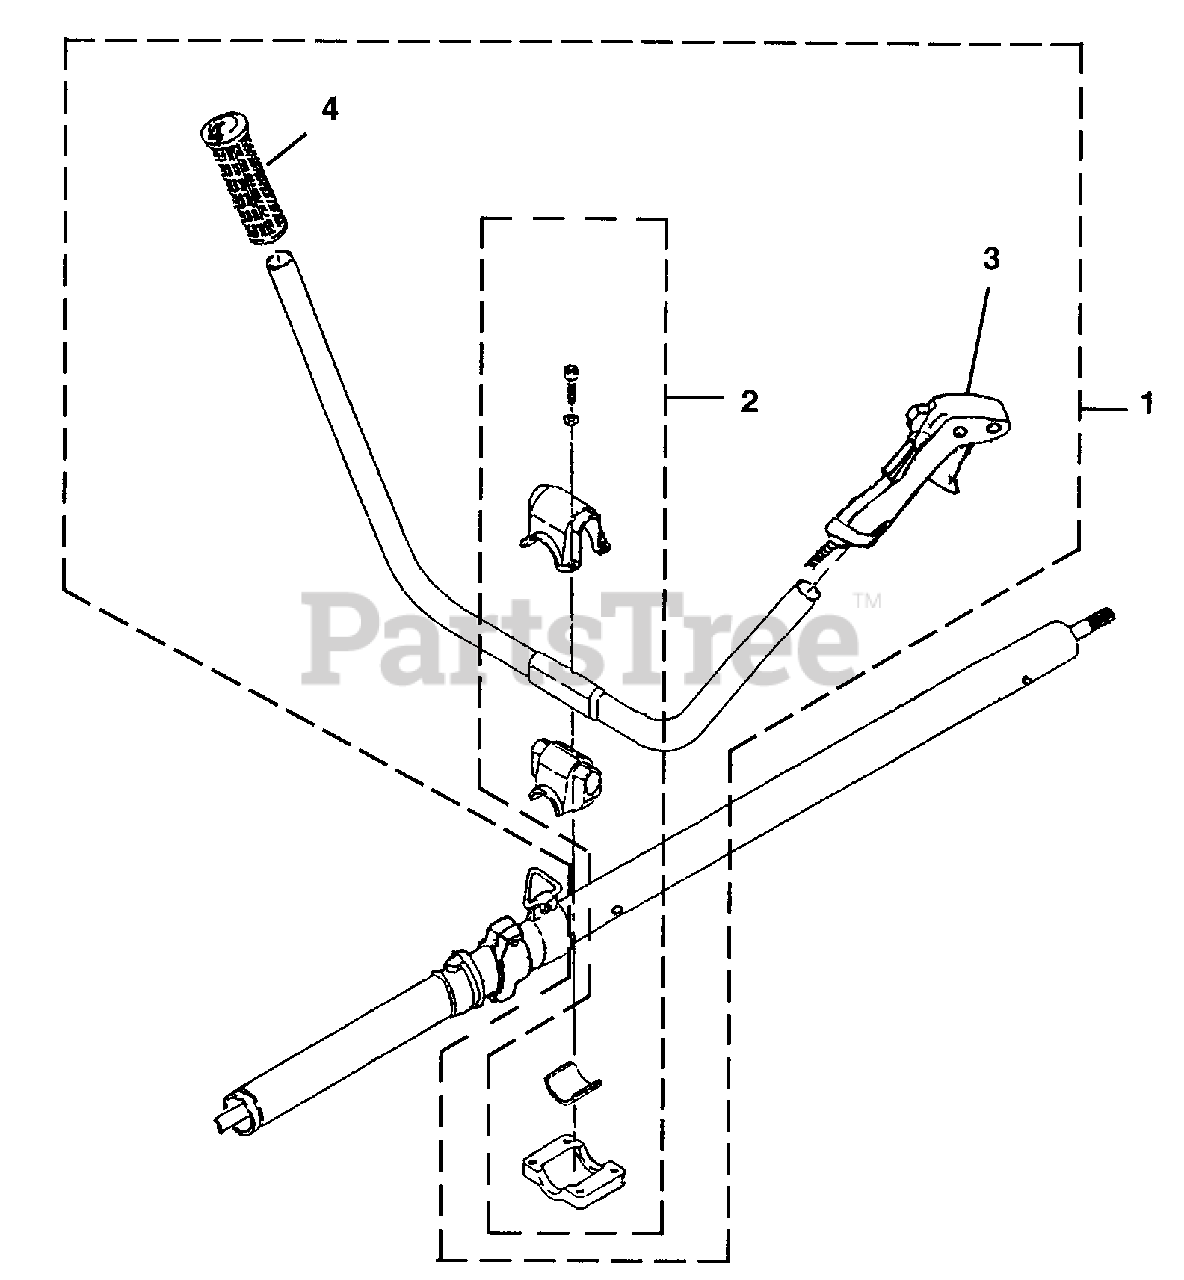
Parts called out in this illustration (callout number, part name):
1	HANDLE ASSEMBLY
2	HANDLE BRACKET
3	CONTROL LEVER
